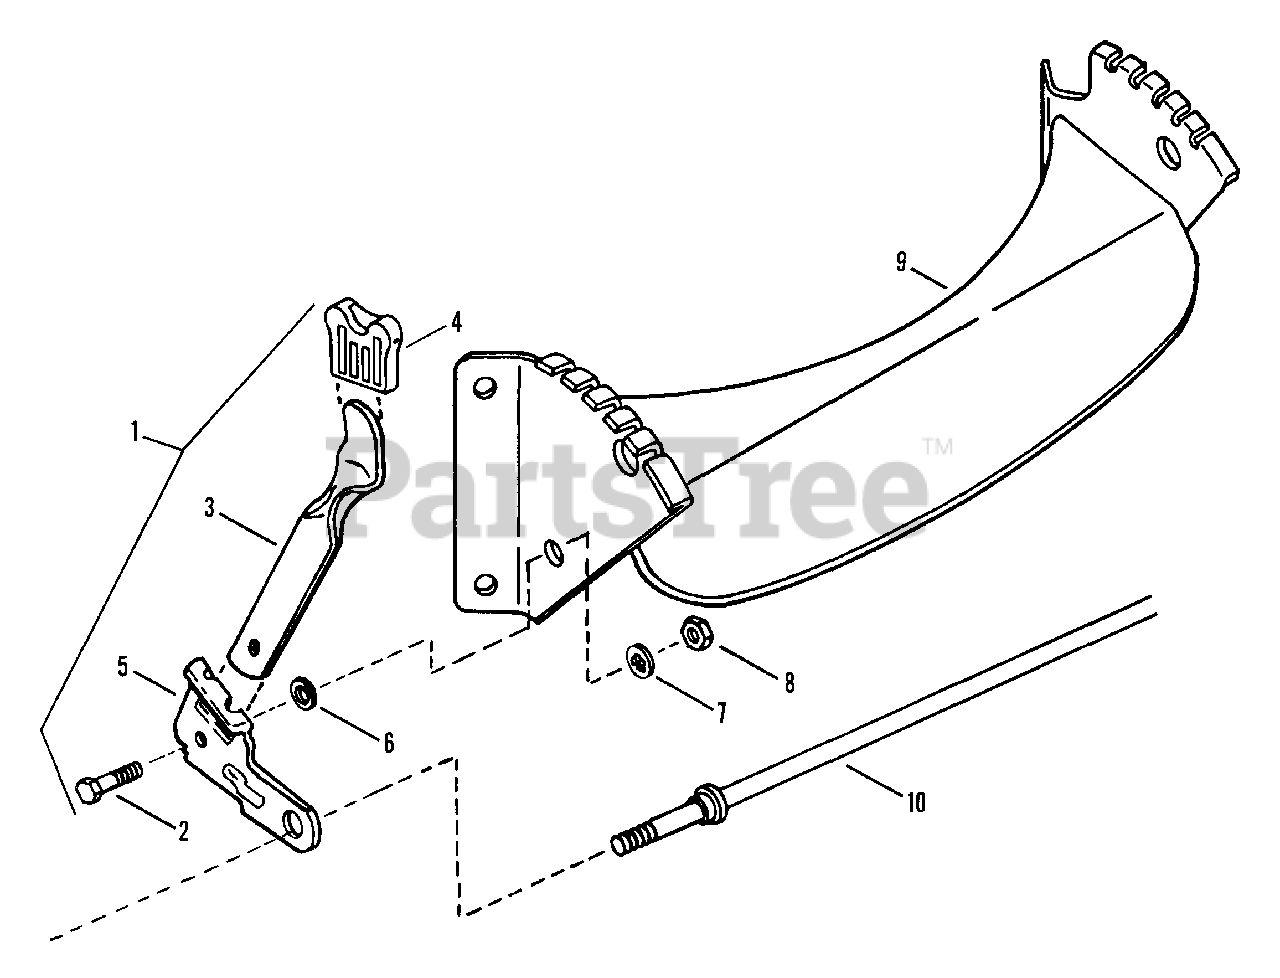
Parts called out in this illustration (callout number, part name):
1	ARM ASSEMBLY, Left Wheel
1	ARM ASSEMBLY, Right Wheel
2	BOLT, 5/16-18 Shoulder
3	LATCH, Height
4	GRIP, Latch
5A	ARM, Left Wheel
5B	ARM, Right Wheel
6	RETAINER, 5/16 Bolt
7	WASHER, 5/16 Internal Tooth Lock
8	NUT, 5/16-18 Hex
9	BRACKET, Front Wheel
10	AXLE
